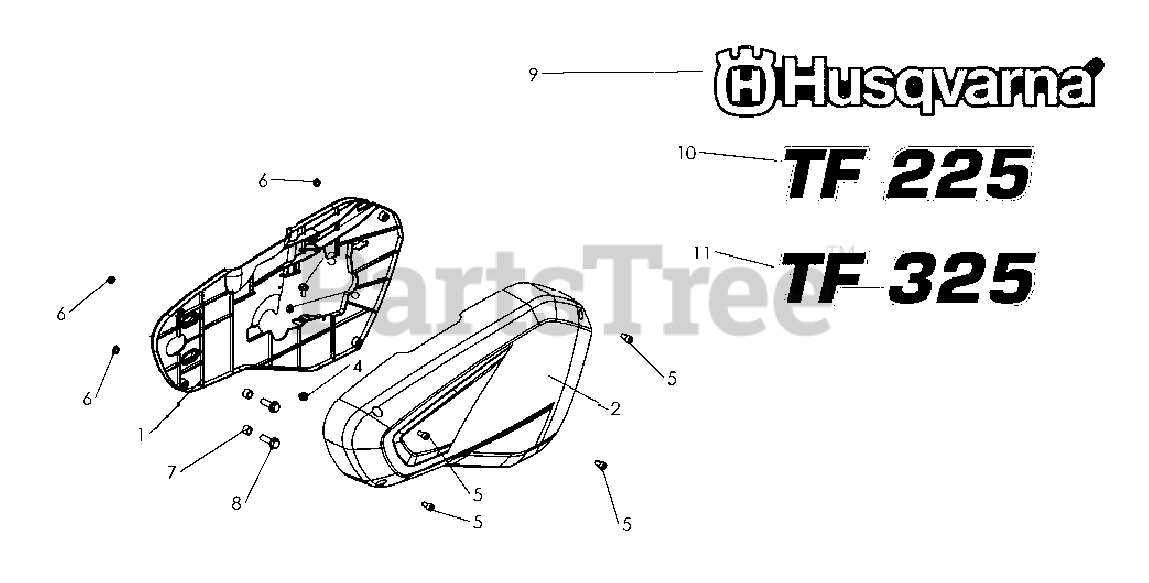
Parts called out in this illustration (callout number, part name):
3	SCREW
4	NUT
6	Blocking nut M 6 Z
